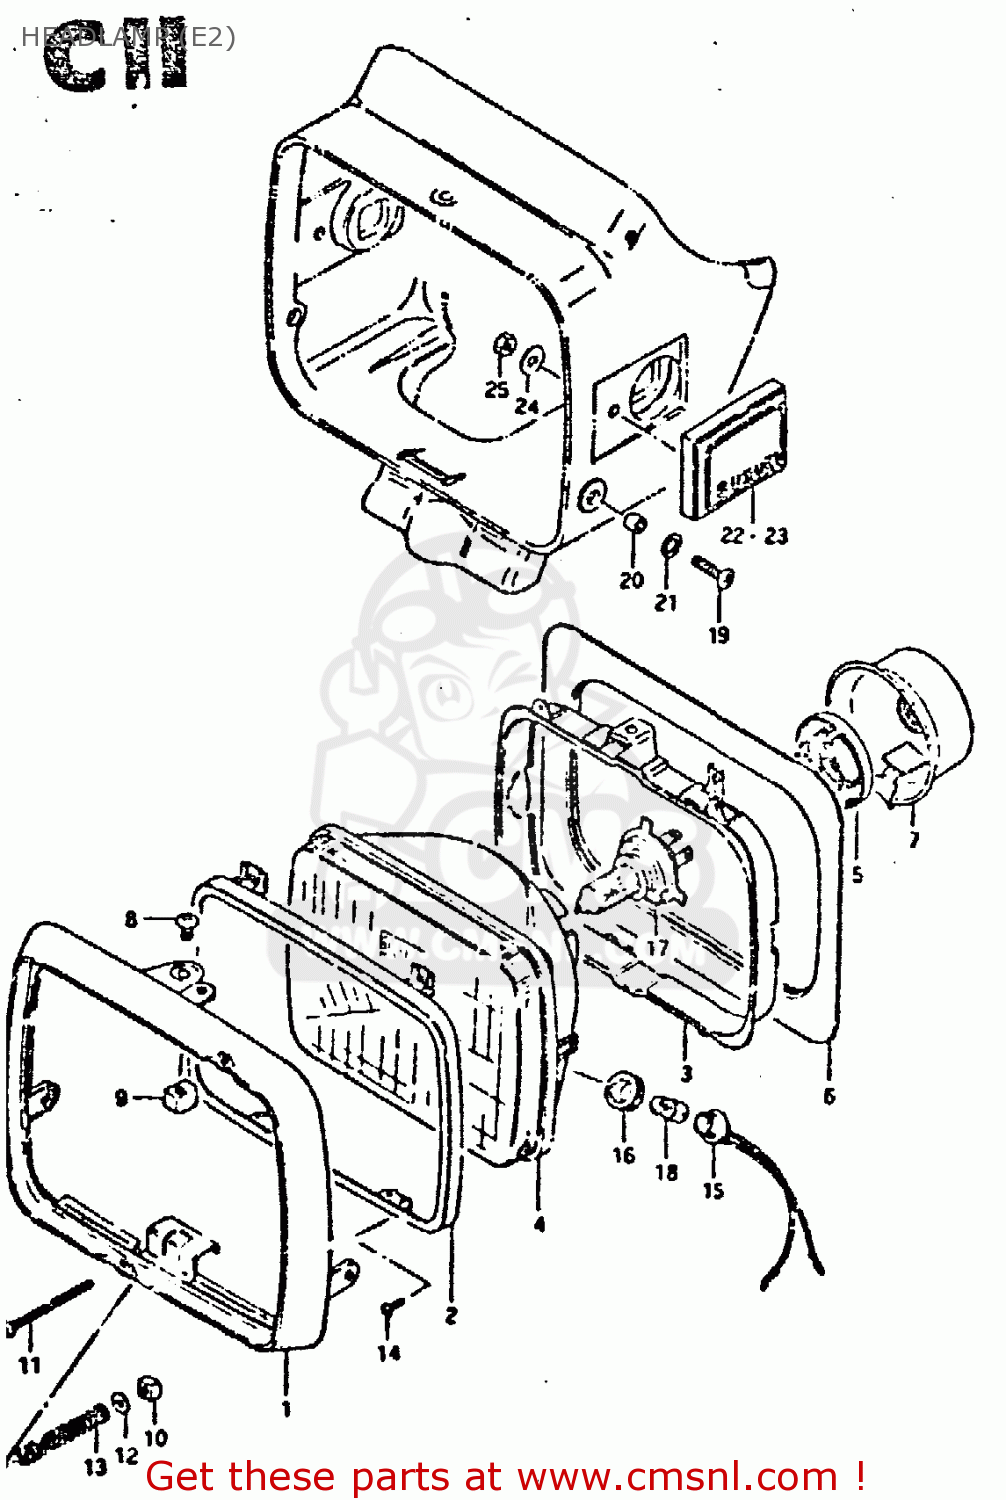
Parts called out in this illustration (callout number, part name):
1	RIM
2	RETAINER,HEADLAMP
3	RING,HEADLAMP UNIT
4	UNIT
5	HOLDER
6	SHADE
7	COVER,HEADLAMP SOCKET
8	SCREW
9	NUT,HEADLAMP ADJUSTER
10	NUT
11	SCREW,HEADLAMP ADJUST
12	WASHER
13	SPRING
14	SCREW
15	SOCKET
16	JOINT,RUBBER
17	BULB(12V60/55W,H4)
18	BULB(12V4W)
19	SCREW
20	SPACER (5.2X8X7.5)
21	GASKET(8.2X12X0.8) (NAS)
22	EMBLEM, FRONT SIDE RH
23	EMBLEM, FRONT SIDE LH
24	WASHER(5.2X16X1)
25	NUT
